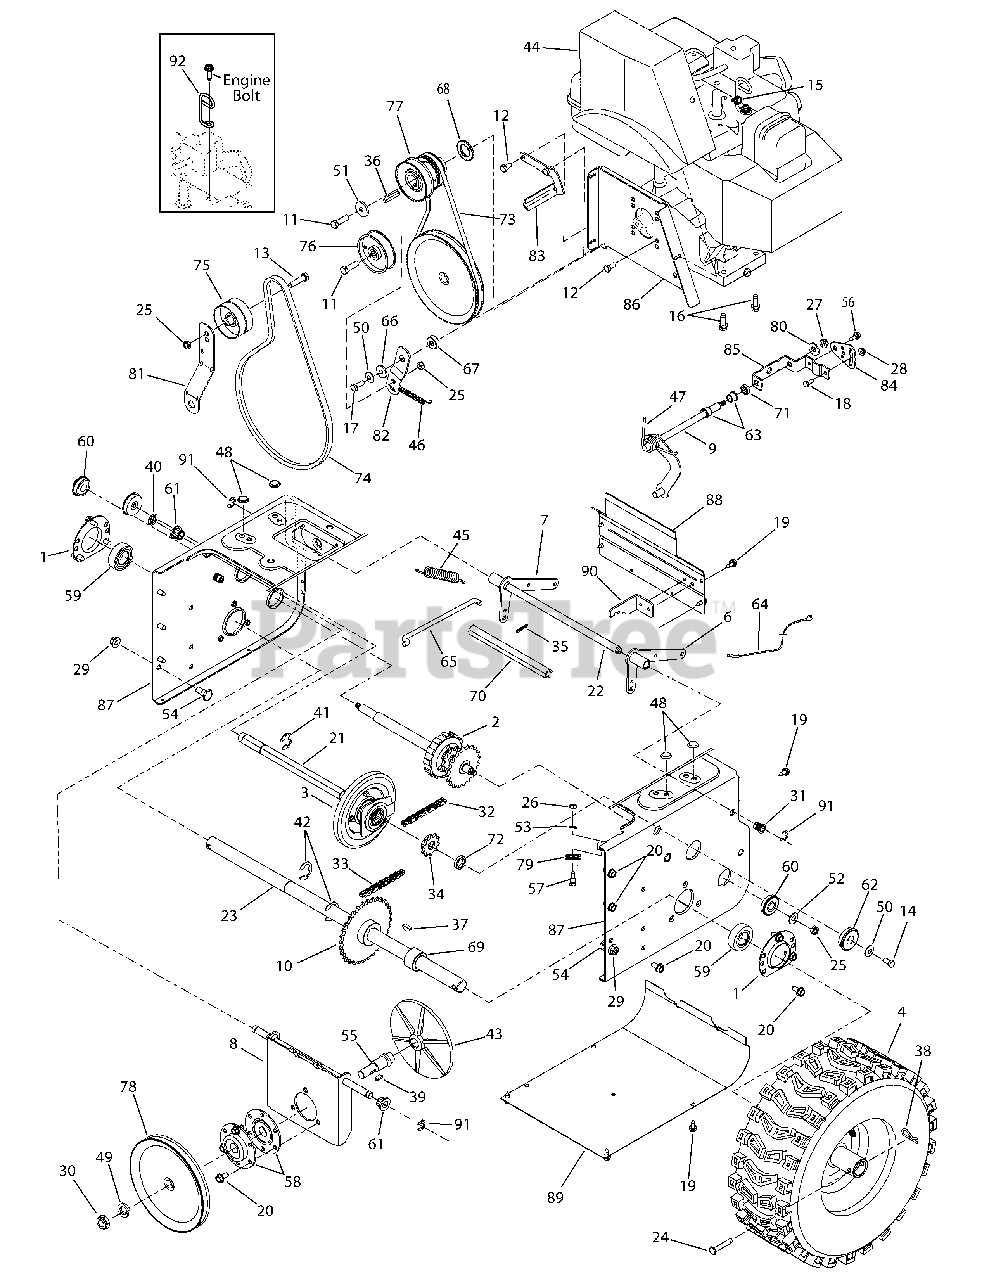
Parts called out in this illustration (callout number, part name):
1	Housing, Bearing
2	Shaft Assembly, Steering
3	Assembly, Friction Wheel
9	Arm, Shift
10	Sprocket, 32T
11	Screw, Hex Cap, 3/8-24 x 1.25 Gr8
12	Screw, Hex Cap, 5/16-24 x .625 Gr5
13	Screw, 3/8-24 x 1.50
14	Screw, Hex Cap Lk, 5/16-18 x .625 Gr5
15	Screw, Hex Tapp, 5/16-18 x .5
16	Screw, Hex Sems Tapp, 3/8-16 x 1.0
17	Scrw, Hx , 5/16-24 x 1.25 Gr5
18	Screw, Hex, 1/4-20 x .620
19	Screw, Hex Wash.
20	TT Screw, 5/16-18 x .750
21	Shaft, Hex Drive
22	Shaft, Actuator
23	Axle, Wheel
24	Pin, Clevis
25	Nut, Hex Insert Jam Lock
26	Nut, Hex, 1/4-28 GR5
27	Nut, Hx Flnge Insert Lk, 5/16-18 GrF
28	Nut, Hx Flnge Insert Lk, 1/4-20 GrF
29	Nut, Hx Flnge Insert Lk
30	Nut, Hx Insert Jam Lk
31	Nut, Insert 3/8-16
32	Chain, Endless, #41 x 36L
33	Chain, #420 x 40L
34	Sprocket, #41 x 10T
35	Pin, Internal Cotter
36	Key, Square, 1/4 x 1.5
37	Key, Woodruff
38	Pin, Internal Cotter
39	Key, Hi-Pro, 3/16 x 5/8
40	Nut, Speed
41	Ring, Retaining
42	Ring, Retainer
43	Plate, Drive
44	Cover, Belt
45	Spring, Extension
46	Spring, Extension, .375 x 3.18
47	Spring, Torsion
49	Washer, Lock, 5/8
50	Washer, Belleville, .34 x .872 x .06
51	Washer, Flat, .406 x 1.25 x .157 HT
52	Wash, .406 x .875 x .059
53	Washer, Lock, 1/4
54	Screw, Shldr., .498 x .34
55	Spindle, Drive Plate
56	Screw, Shoulder, .368 x .113:1/4-20 TT
57	Screw, Hex Shldr., 1/4-28
58	Ass’y, Bearing/Housing
59	Bearing, Self Aligning
60	Bearing, Ball
61	Bearing, Hex Flange
62	Bearing, Ball
63	Bush, Flg, .5 ID x .627 OD
64	Cable, Auger Idler
65	Rod, Drive Clutch
66	Spacer, Shoulder
67	Spacer, .331 x 1.01 x .36
68	Spacer, 1.02 x 1.63 x .1425 - 30" ON
69	Spcr., 1.0 ID x 1.50 OD
70	Spcr., .51 ID x 7.895 Lg.
71	Spacer, .5151 x .75 x .22
72	Spacer, .675 x 1.0 x .23
73	V-Belt, 3/8 x 34.4
74	V-Belt, 1/2 x 42.0
75	Idler, Flat, 2.75 OD
76	Pulley, Flat Idler, 3.0 OD
77	Pulley, Dbl, 3.25 OD
78	Pulley, Drive
79	Roller, Cable
80	Washer, Flat, .469 x .875 x .105
81	Brkt., Idler, Auger
82	Bracket, Idler, Drive
90	Bracket, Planetary Lock
91	E-Ring
92	Guide, Control Cable
